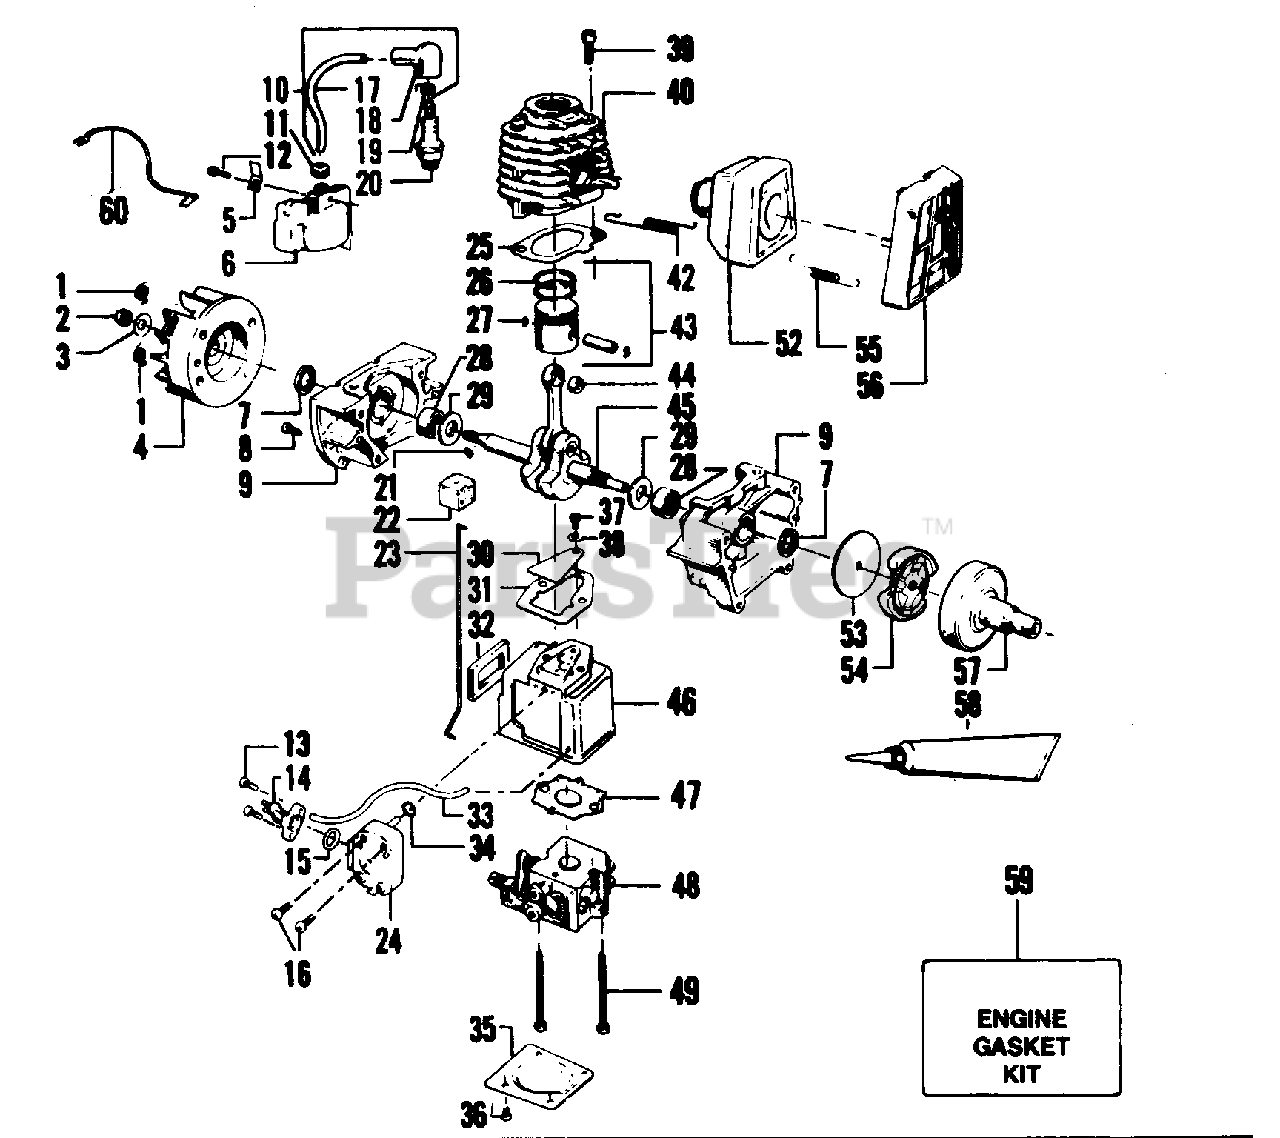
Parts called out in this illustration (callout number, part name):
1	Spring - Starter Dog
2	Nut - Flywheel
3	Washer - Flywheel
4	Flywheel Assembly (Incl. #1)
5	Tab 45ø Electrical
6	Kit - Ignition Module
7	Seal - Crankcase
8	Screw - Crankcase - 10 - 24 x 5/8
9	Crankcase Assembly (Incl. #7 & 28)
10	High Tension - Lead Assembly (Incl. #17, 18 & 19)
11	Grommet - Plug Wire
12	Screw - 8 - 32 x 3/4 - Fil. Hd. - Ignition Module
13	Screw - 8 - 16 x 9/16
14	Cap Assembly - Accumulator (Incl. Cap, Screen & "O" Ring))
15	O - Ring - Accumulator Chamber
16	Screw - 8 - 8 x 1" - Accumulator
17	High Tension Lead Wire
18	Boot - Spark Plug
19	Connector - Spark Plug Lead
20	Spark Plug (CJ-14)
21	Key - Flywheel
22	Boot - Throttle
23	Throttle Wire (Red)
24	Accumulator Assembly (Incl. # 14, 15 & 34)
25	Gasket - Cylinder
26	Ring - Piston
27	Retainer - Wrist Pin
28	Bearing - Crankcase
29	Washer - Thrust - Crankcase
30	Reed Valve
31	Gasket - Carburetor Case to Crankcase
32	Seal - Carburetor Case
33	Line Kit
34	O - Ring (Orifice)
35	Cover - Carburetor Case
36	Screw - 8 - 18 x 9/16 - Pan Hd. Carburetor Case Cover
37	Screw - 6 - 19 x 5/15 - Pan Hd. - Reed Valve
38	Washer - Reed Valve Screw
39	Screw - 1/4 - 20 x 3/4 - Hex Socket Hd. Cylinder
40	Cylinder
42	Spring - Muffler Detachment
43	Piston Kit (Incl. #26, 27 & Pin)
44	YP130 Type 1
44	YP130A Type 2 :YP130A - Type 1
45	YP130 Type 1
45	YP130A Type 2 ;YP130A - Type 1
46	Carburetor Housing
47	Gasket - Carburetor
48	Carburetor (See Carb.Breakdown for Ass'y)
49	Screw - 10 - 24 x 2-1/4" - Fil. Hd. - Carburetor
53	Kit - Clutch Washer - 3/8 - Flat - Inner
54	Clutch Assembly Kit
55	Spring - Muffler Guard
56	Guard - Muffler
57	Coupling & Bearing Assembly
58	Sealant - Crankcase (Not Supplied with Unit)
59	Engine Gasket Kit
60	Lead Wire - Kill Switch
